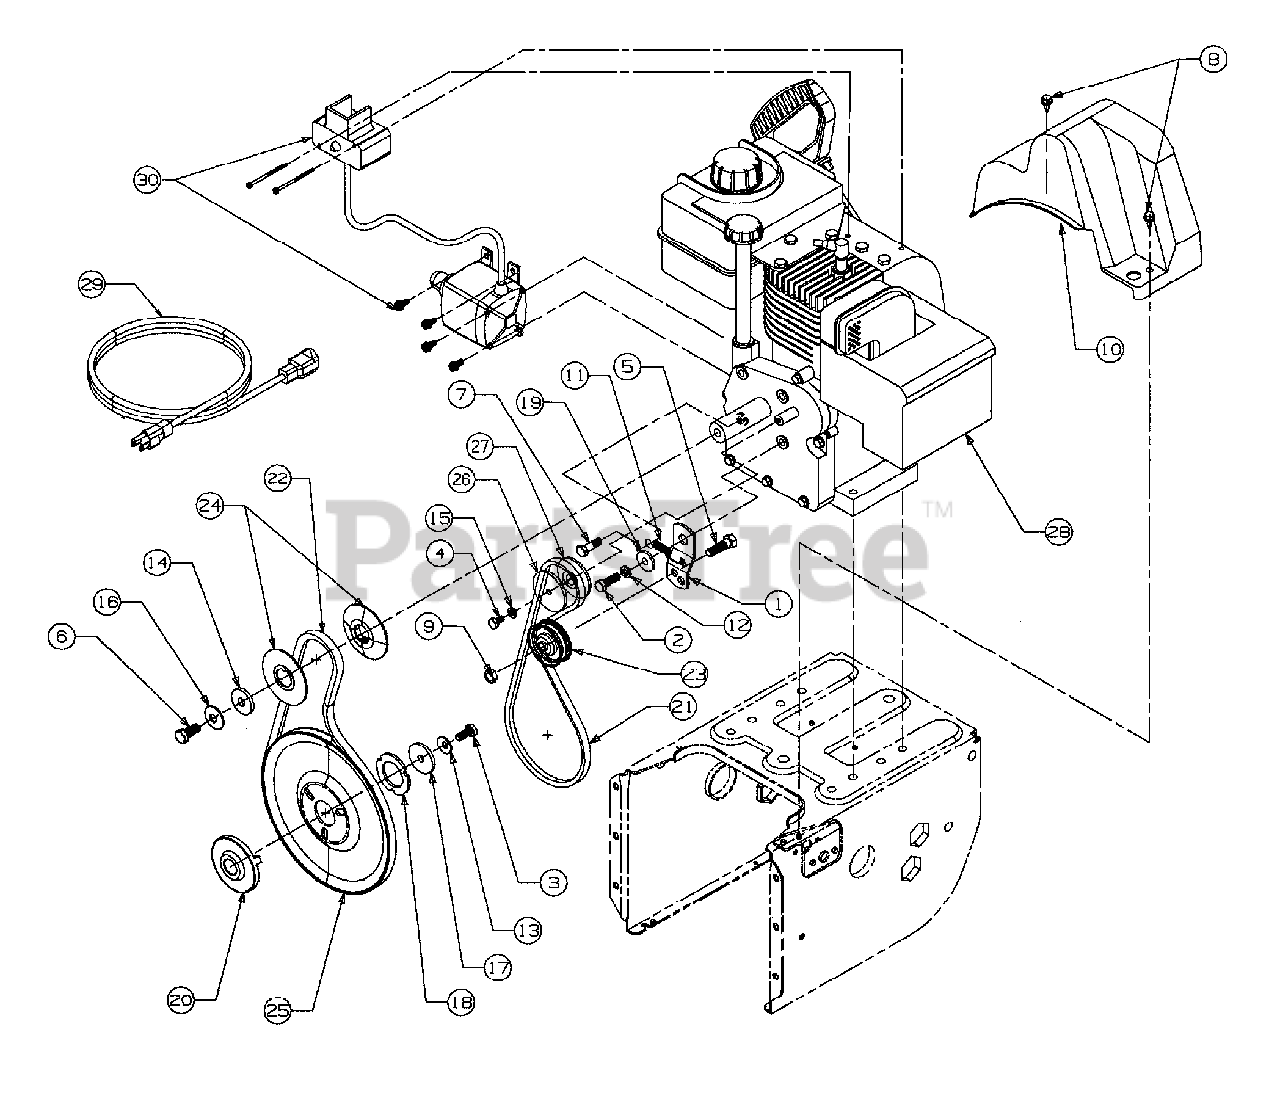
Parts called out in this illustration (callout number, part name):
3	Screw
4	Screw
5	Screw
6	Screw
7	Screw
8	Screw
9	Nut, Hex Jam
10	Belt Cover
11	Spring
12	Washer
13	Washer - Bell
14	Washer
15	Washer
16	Washer - Bell
17	Washer - Flat
18	Washer
19	Spacer
20	Pulley, Adapter
21	V-Belt
22	V-Belt Matched
23	Idler, Flat
24	Pulley, Half
25	Pulley, Auger
26	Pulley Half
27	Pulley, Half
28	Engine
29	Cord Extension
30	Starter
